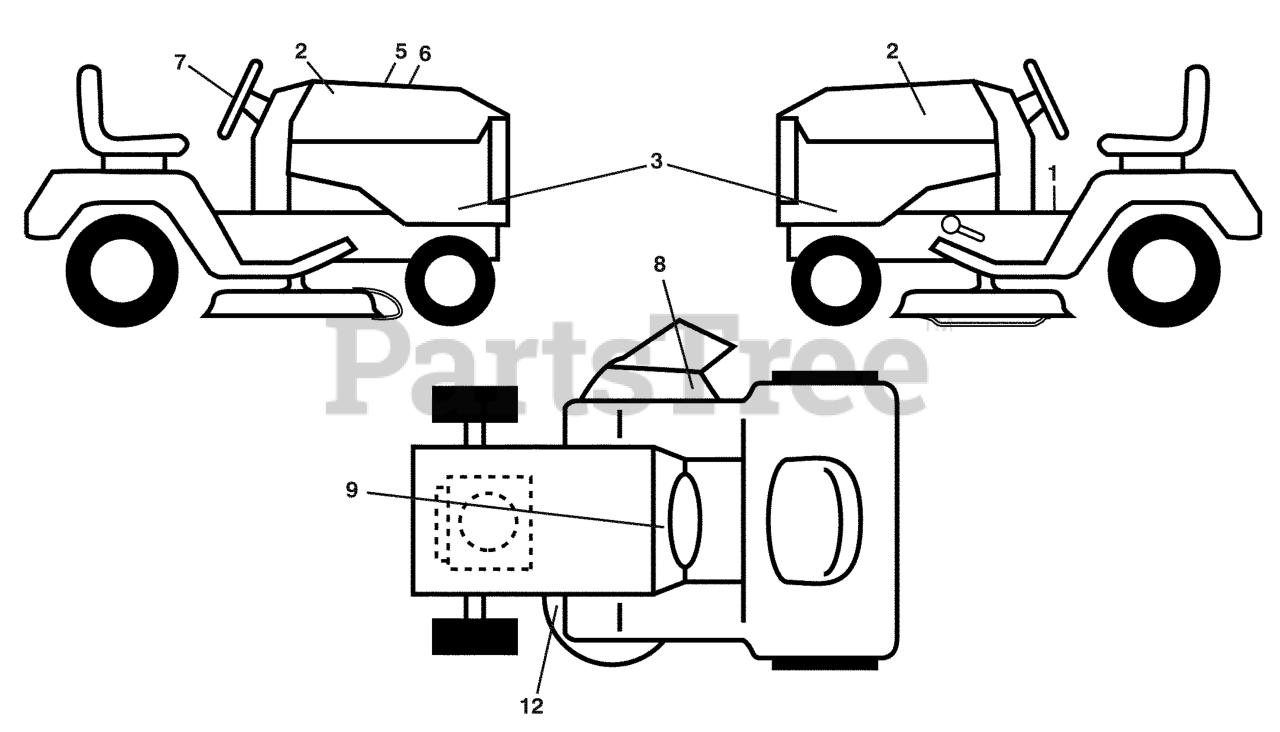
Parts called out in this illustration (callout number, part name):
1	DECAL.FENDER.WARNING.ENG
2	DECAL.HOOD.LOGO.HUSQVARNA
3	Decal, Hood Panel SD
5	DECAL HOOD CUST. RESP.
6	Decal, Replacement
7	DECAL.WHEEL.STRG.LGN.H
8	DECAL.WARN.KEEP.HAND.AWAY
9	DECAL BTRY SYMBOLS
12	DECAL V BELT SCHEMATIC
